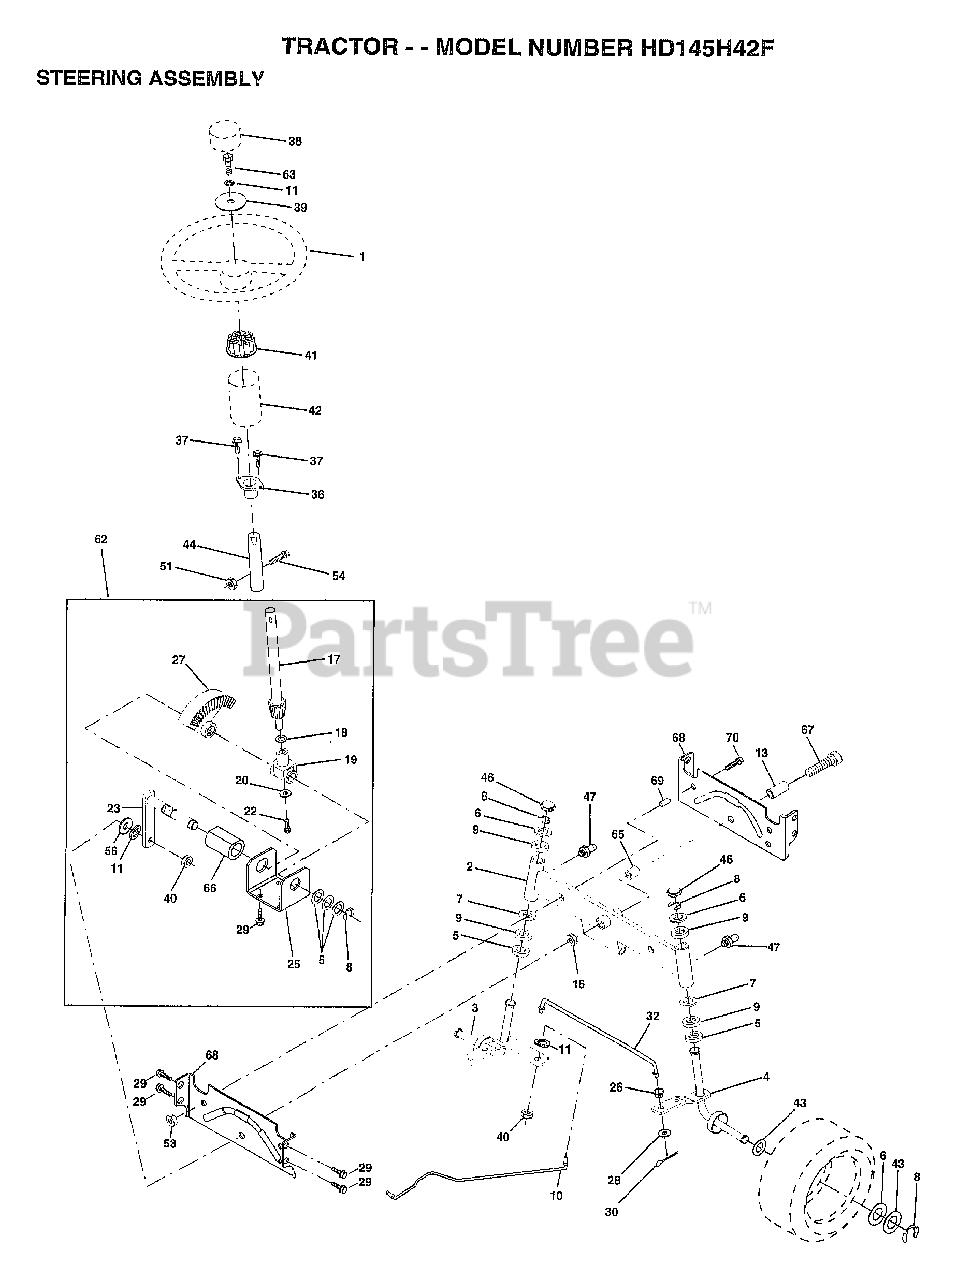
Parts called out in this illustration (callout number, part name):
2	SPRING.BRAKE.RETU
5	STRAP TORQUE
6	SCREW
8	ROD SHIFT FEND LT
10	PIN COTTER 1/8
11	WASH-SHFT PLT LT
13	BOLT.1/4-28.W/PAT
15	BOLT.HX.FLG.5/16
18	BOLT
19	NUT
21	KNOB T (1/2-HOLE)
22	BRAKE ROD
24	NUT
25	SPRING ROD LT
26	WASHER
27	COTTER PIN
28	ROD.BRAKE.PARK.LT
29	PLUNGER CAP T
30	TRANSAXLE MTG BKT
32	BOLT
34	SHAFT ASM-PEDAL F
35	NYLON BEARING
36	WASHER LT
38	PULLEY.IDLER.FLAT
39	BOLT
40	SPACER T
42	WASHER
43	WASHER T
48	BELLCRANK ASM
49	RETAIN BELT
53	"LINK, CLUTCH T"
55	"SPRING, RETURN LT"
57	"V-BELT,GRD DRIVE"
59	KEEPER BELT CNTSP
61	SCREW
62	PEDAL COVER T
63	PULLEY.ENGINE
64	BOLT
65	LOCKWASHER
66	KEEPER-BELT
69	SCREW HEXWSH H-L
70	KEEPER BELT ENG
72	WASHER
74	"SPACER AXLE,PVST"
75	WASHER
76	E-RING LT
77	SQUARE KEY
78	WASHER
81	SHAFT ASM CROSS
82	"SPRING,TORSION"
83	WASHER
84	ROD TIE
86	BUSHING
87	WASHER D
88	KLIP RING
95	ROAD ASM BYPASS
96	RETAINER M
113	"STRAP,TORQUE"
116	BOLT RDHD 3/8-16
118	SPACER-BELLCRANK
121	NYLINER-CLUTCHING
122	"PLATE-BYPASS,PVST"
124	SPRING RETURN
143	BOLT
144	WASHER
